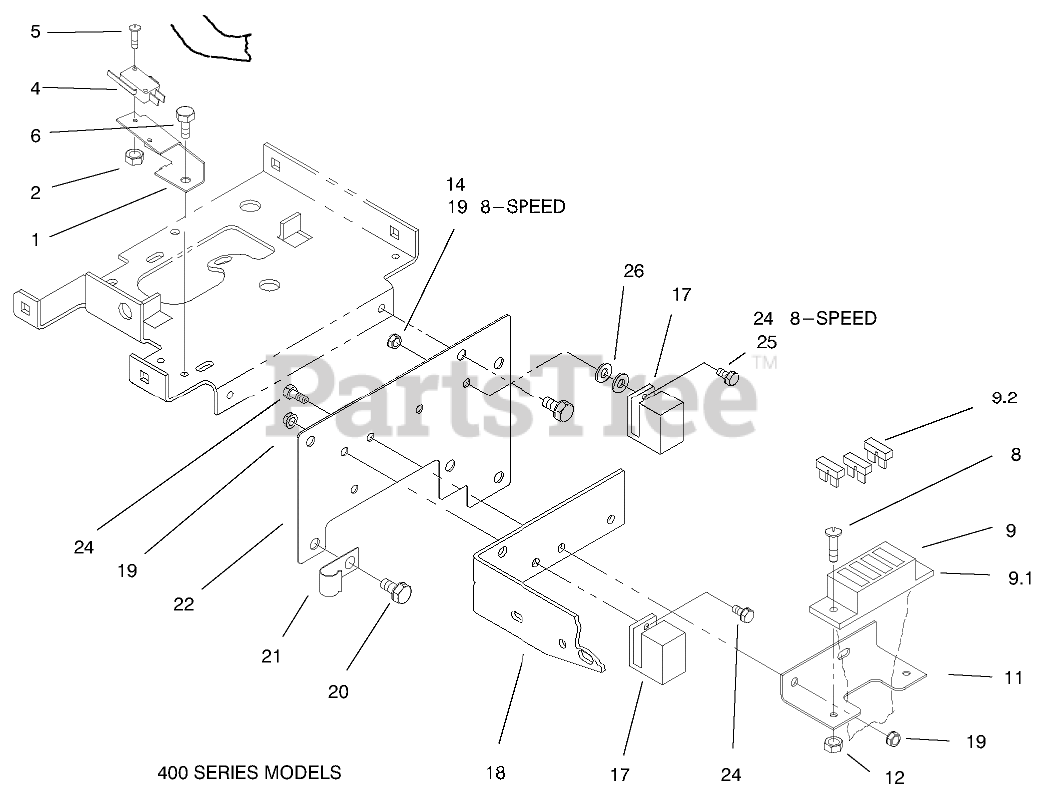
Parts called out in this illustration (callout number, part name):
1	NUT-HEX
2	BRACKET-SWITCH
4	SWITCH
5	SCREW-PHL 4-40X1 1/4
6	SCREW-HWH
8	SCREW-PAN
9	WIRING-HARNESS & DIA
9:1	FUSE-HOLDER 4 WAY
9:2	FUSE-BLADE, 25 AMP
9:2	FUSE-BLADE, 15 AMP
9:2	FUSE-30 AMP
11	Bracket-Fuse Holder
12	Nut
14	NUT-LOCK, NI
17	RELAY
18	BRACKET-BELT (BLACK)
19	NUT-LOCK, NI
20	Bolt
21	CLIP
22	PLATE-FRONT HOODS (BLACK)
24	SCREW-HHF
25	SCREW-HHF
26	WASHER-FLAT
